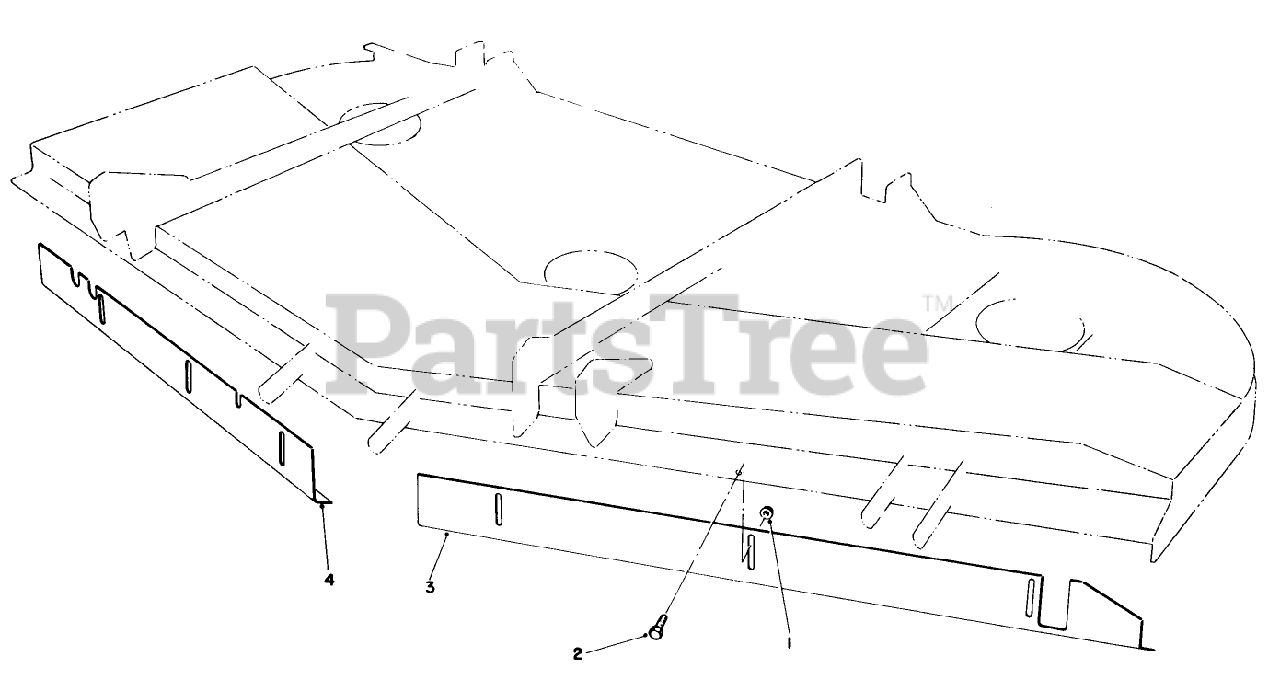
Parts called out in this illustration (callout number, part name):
1	NUT-HF
2	SCREW-HH
3	Baffle-Front LH
4	Baffle-Front RH
